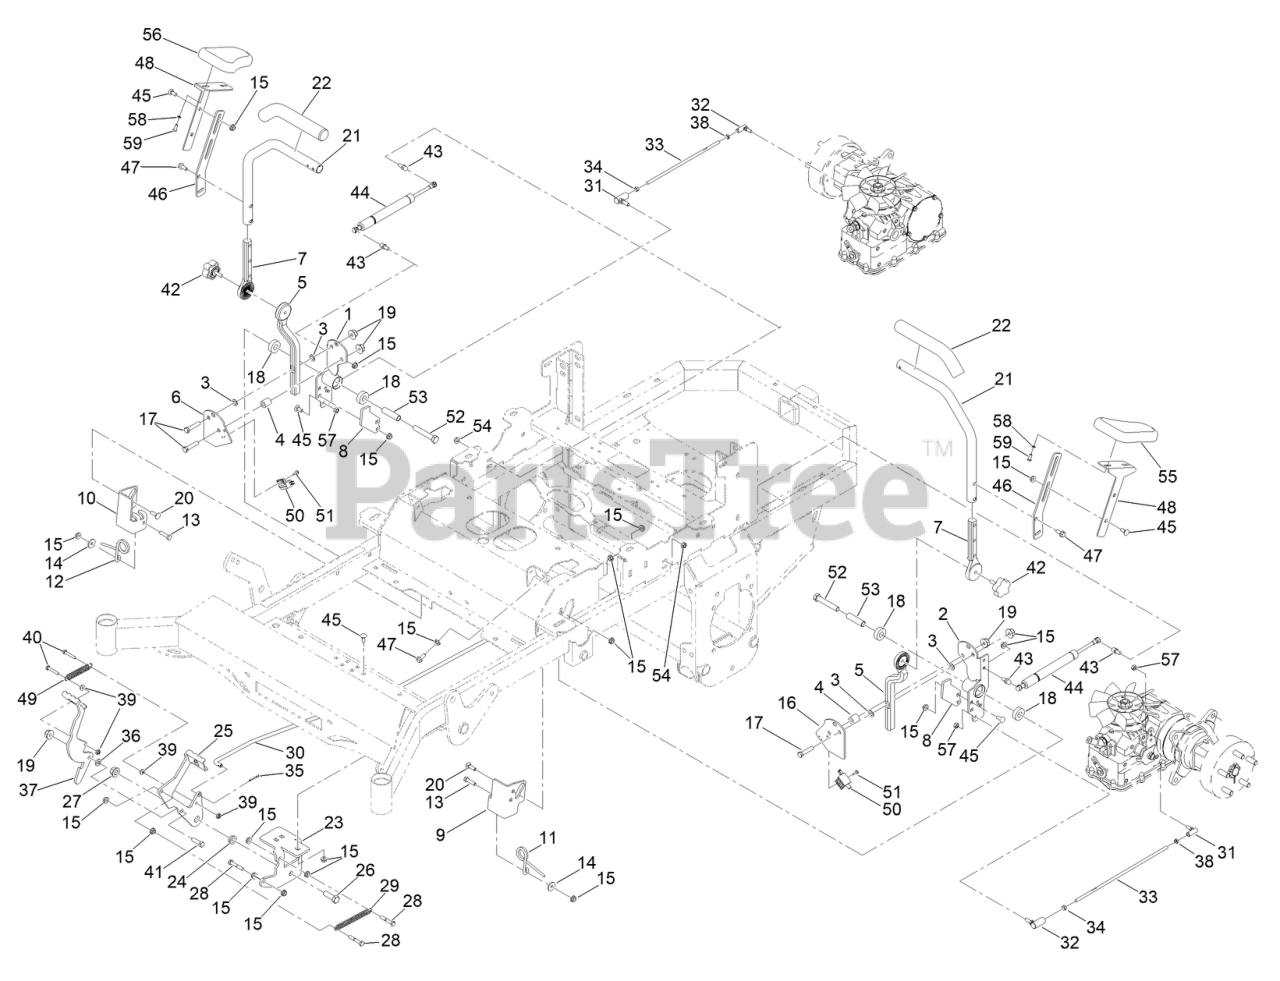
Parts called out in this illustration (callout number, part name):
1	RT DRIVE ARM BRKT ASSY PAINTED BLACK
2	MWR LT DRIVE ARM BRKT ASSY
3	3/8 X 3/4 BRONZE WASHER
4	MWR DRIVE ARM SPACER
5	ADJUSTABLE LWR DRIVE ARM
6	MWR RT CTRL ARM LIMIT SWTCH PLATE BLACK
7	ADJUSTABLE UPP DRIVE ARM
8	REVERSE DETENT KICK PLATE PAINTED BLACK
9	REV DENTENT SPRING BASE (LH)
10	REV DENTENT SPRING BASE (RH)
11	SPRING- LT REVERSE DETENT
12	SPRING-TORSION
13	SCREW-HH
14	STRIKER POST FENDER WASHER
16	MWR LT CTRL ARM LIMIT SWTCH PLATE BLACK
17	3/8-16 X 1-3/4 HEX C/S GR 2 ZINC
18	5/8IN ID X 1-3/8IN OD X 7/16IN THK BRG
19	3/8-16 NYLON INSERT FLANGE L/NUT YZ
20	5/16-18 X 1 CARRIAGE BOLT GR 8 YZ
21	MOWER DRIVE HANDLE TUBE ABC
22	CONTROL ARM HANDLE GRIP
23	MWR FRAME BRAKE MTG BRKT BLACK
24	1/2IN ID X 3/4IN OD X 3/8IN FLANGE BUSH
25	MWR BRAKE LOCK LEVER ASSY BLACK
26	SCREW-HH
27	NUT-LOCK
29	2020 MWR BRAKE PEDAL TENSION SPRING
30	MWR BRAKE LINKAGE
31	BALLJOINT-RH (W/GROMMET)
32	CONTROL ARM ROD END LT
33	TRANS DRIVE ARM LINKAGE STANDARD TRANS
35	PIN-COTTER
36	3/8 ID X 3/4 OD X .125 THK BRONZE WASHER
37	MWR BRAKE UNLOCK LEVER ASSY BLACK
38	NUT-JAM
39	1/4-20 HEX FLANGE NUT
40	1/4-20 X 1-1/4 HEX C/S GR 2 ZINC
41	SCREW-HH
42	5/16-18 X 1 SL 5-LOBE MALE ST KNOB 1.90
43	5/16-18X1.286 DAMPER BALL STUD (.562 TL)
44	CONTROL ARM DAMPER
45	BOLT-CARR
46	MWR ARM PAD TUBE MTG BRKT BLACK
47	SCREW-HHF
48	MWR ARM PAD MTG BRKT BLACK
49	MWR BRAKE PEDAL RELEASE SPRING
50	NO PLUNGER LIMIT SWITCH
51	8-32 X 1/2 IND. HWH SLOT TYPE F TCS ZINC
52	1/2-13 X 3 HEX C/S GR 5 ZINC W/LOCTITE
53	MWR DRIVE ARM HUB / DECK LIFT ARM SPACER
54	5/16-18 NYLON INSERT FLANGE L/NUT ZC
55	2020 MWR DRIVE ARM SUPPORT PAD LT
56	2020 MWR DRIVE ARM SUPPORT PAD RT
57	5/16-24 NYL INS L/N GR.8 ZC/YEL
58	1/4 EXT TOOTH LOCKWASHER ZINC
59	SCREW-HSBH
